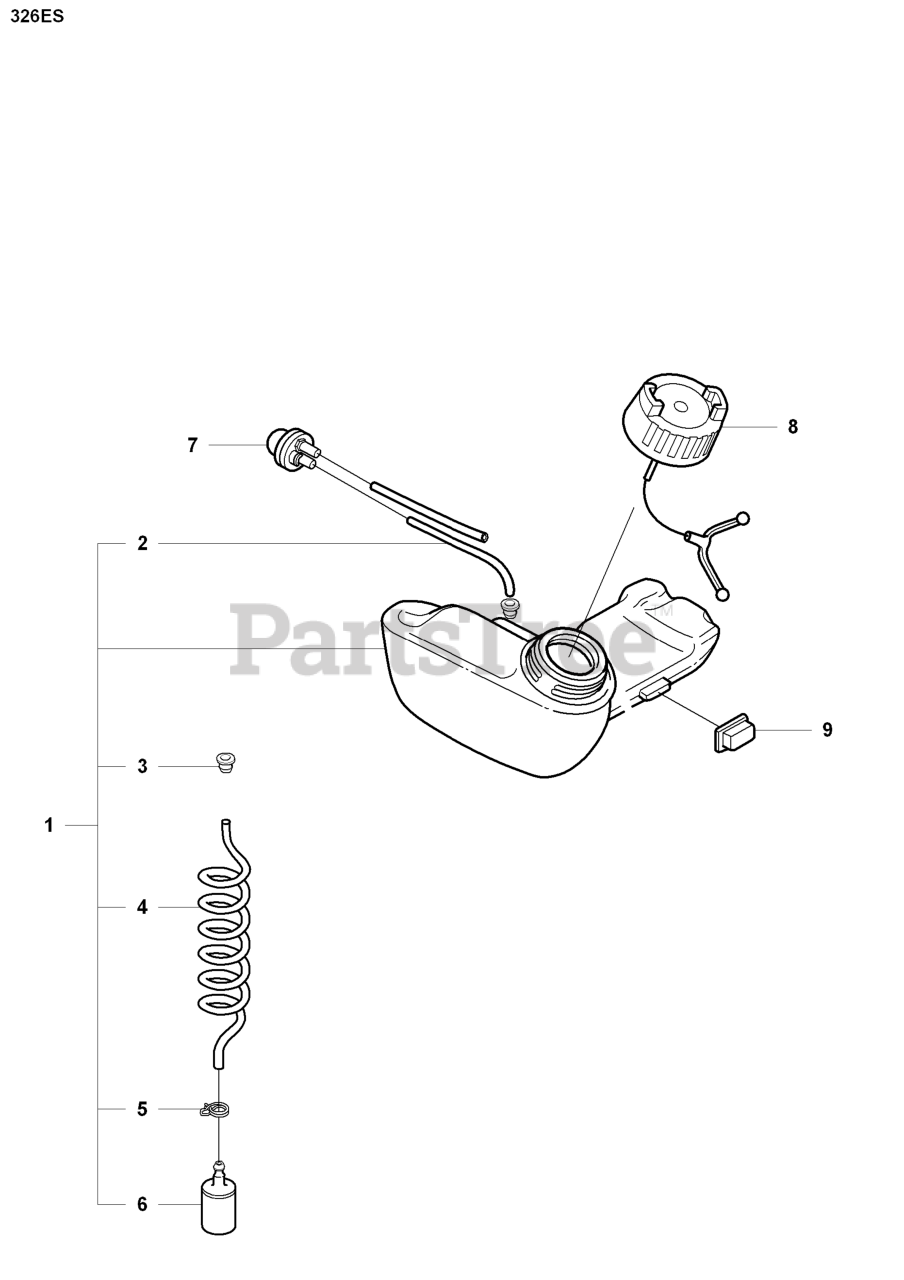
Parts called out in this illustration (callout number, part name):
2	HOSE.FUEL L=102
3	FUEL TANK BUSHING
4	FUEL HOSE
5	HOSE CLAMP
6	RP FUEL FILTER
7	AIR PURGE BUBBLE
8	%FUEL CAP
